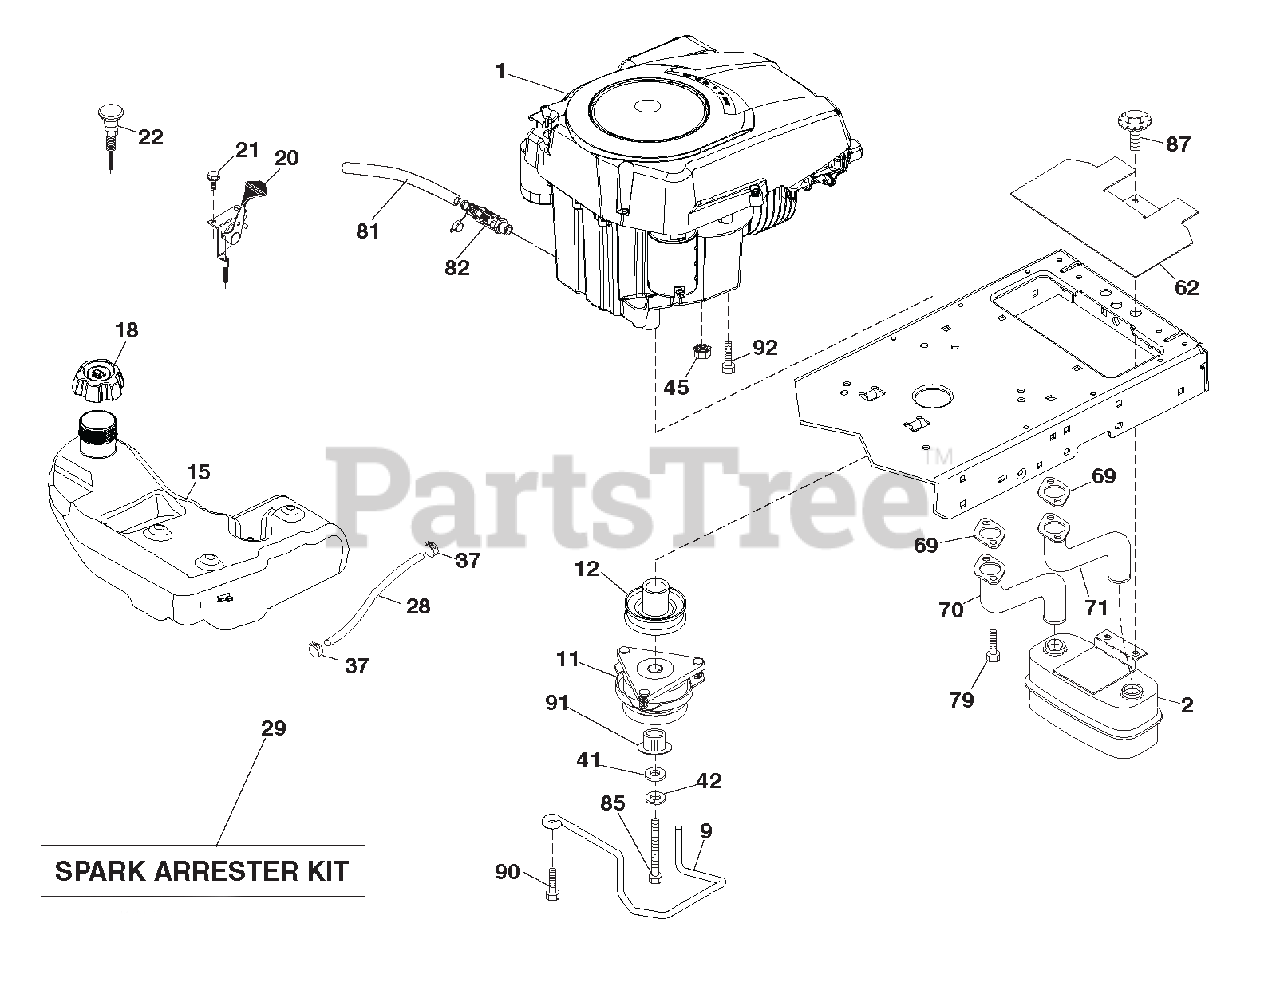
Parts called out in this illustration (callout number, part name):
1	ENGINE KOHLER MODEL NO. SV715-3026 (438350) (ORDER PARTS FROM ENGINE MANUFACTURER.)
2	MUFFLER ASM.TWIN.LO-TONE
9	KEEPER.BELT.ENGINE.4.25"NSTG
11	CLUTCH.ELECTRIC
12	PULLEY.ENGINE
15	TANK.FUEL.SIDE-FILL.3.00 GA.
18	CAP FUEL
20	CONTROL.THROTTLE
22	CONTROL CHOKE
28	LINE.FUEL.64"REAR.EMIS.CA.LP
29	KIT.SPARK ARRESTOR(392390 B&S)
37	CLAMP.HOSE.BLK.
41	WASHER.1-1/2 ODX15/32 IDX.250
42	WASHER.LOCK.HVY HLCL.SPR.7/16
45	Nut, Keps Hex 1/4-20 unc
62	SHIELD.HEAT.MUFFLER.
70	PIPE.EXHAUST.LH.CV18/20
71	PIPE.EXHAUST.RH.CV18/20
79	SCREW.SOCKET HD.5/16-18 X .75
81	TUBE.DRAIN.OIL.EASY
82	VALVE OIL DRAIN
85	BOLT.HEX.7/16-20 X 3.75 X GR.
87	BOLT.5/16-18 UNC X 1 W/SEMS.BL
90	SCREW.3/8-16X1.SMGML.TAP/R.BLK
91	BUSHING.1.375OD.HEYCO 2210
92	SCREW.3/8-16 X 1.SMGML.TAP/R
